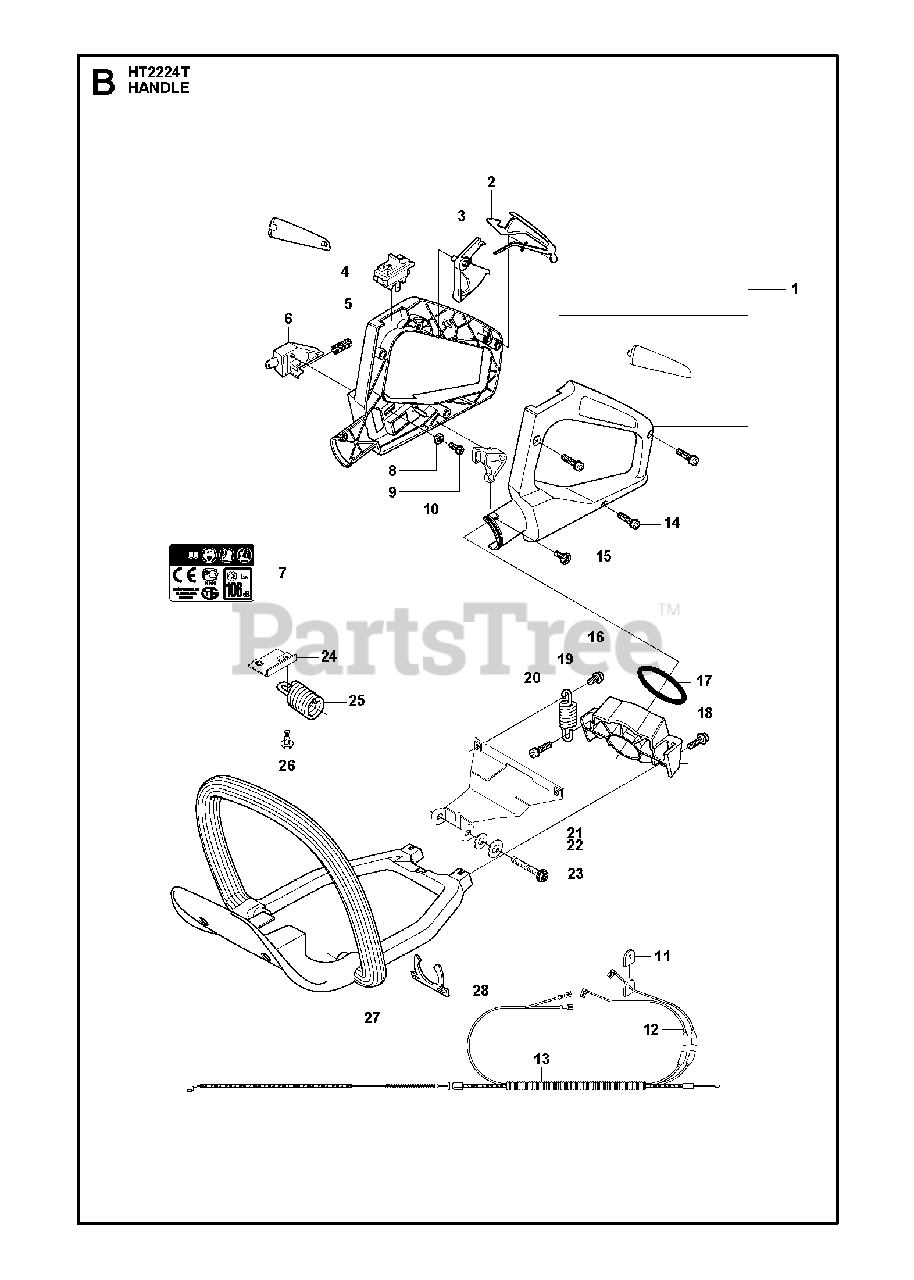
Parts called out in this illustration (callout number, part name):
4	START/STOP SWITCH
12	SHORTING LEAD
13	WIRING ASSY
16	SCREW M5 X 10
19	VIBRATION ABSORBER
22	WASHER - M6
25	VIBRATION ABSORBER
26	SCREW M5 X 10
